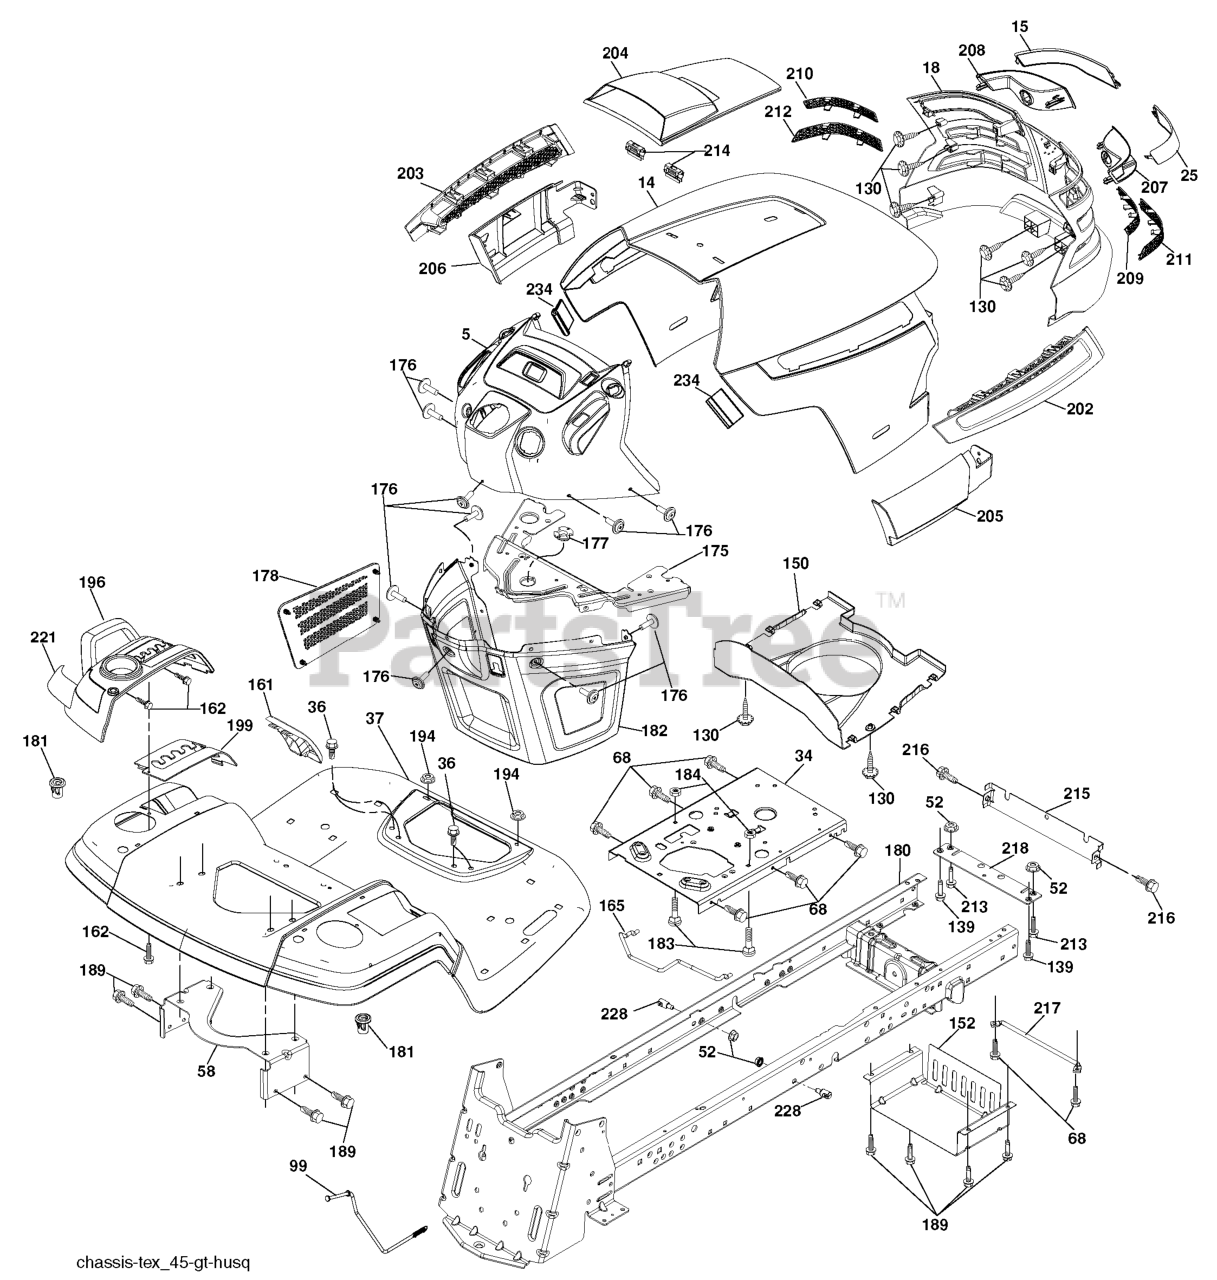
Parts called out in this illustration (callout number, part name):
5	DASH.HUSQ.UPR.ELE.SVMD
14	HOOD.PNT.HUSQVARNA.GT.
15	LENS.LH.TEX.GT.HUSQ.CL
18	GRILLE.ASM.TX.GT.HUSQ
25	LENS.RH.TEX.GT.HUSQ.CL
34	PLATE.ENGINE.WELDED.CHASSIS
36	SCREW 5/16"
37	FENDER.PNT.TX.GT.CH/FW.ORANGE
52	LOCKNUT
58	BRKT.SUPPORT.FNDR/TANK
68	Screw 5/16-18 x 1/2
99	ROD.ASM.BYPASS.0610.FE
130	SCREW
150	AIR.DUCT.TEXGT.HUSQ.SV
152	SHIELD.BROWNING.WTEXLT
161	CONSOLE.FUEL.WINDOW.HU
162	SCREW.HI-LO.CONSOLE
165	SUPPORT.TANK.REAR.W/TEX
175	PLATE.CROSSMEMBER.HUSQ
176	SCREW.#10-24X5/8.RN.QU
177	BUSHING, STEERING
178	CARGO.ASM.NET.TXGT.W/C
179	PLUG.N/CRUISE.COMMON.YT/GT.BLK
180	CHASSIS.WLDMT.TX.GT.05
181	BUSHING.MNT.FEND.CRGO.
182	DASH.LOWER.COMMON.12V.
183	BOLT.5/16-18X1-1/4 FULL.THREAD
184	SPACER.FENDER
189	SCREW
194	NUT LOCK HEX FLANGE 5/16-18
196	RP CONSOLE.ASM.DECKLFT.W/
199	PLATE.DECK.LIFT.HUSQVARNA.GT
202	VENT.SIDE.HOOD.HUSQ.RH.GREY
203	VENT.SIDE.HOOD.HUSQ.LH.GRAY
204	VENT.TOP.HOOD.HUSQVARN
205	SKIRT.HOOD.SIDE.HUSQ.RH.GREY
206	SKIRT.HOOD.SIDE.HUSQ.LH.GREY
207	BEZEL.RH.TEX.GT.HUSQ
208	BEZEL.LH.TEX.GT.HUSQ
209	INSERT.HEX.GRILL.HUSQ.GREY
210	INSERT.HEX.GRILL.HUSQ.
211	INSERT.HEX.GRILL.HUSQ.
212	INSERT.HEX.GRILL.HUSQ.
213	BOLT
214	CLIP.RETAINER.TINNER.
215	COVER.CHASSIS.FRONT.WE
216	SCREW, 5/16-18 X 1/2
217	ROD PIVOT CHASSIS/HOOD
218	X-PIECE.HOOD.STOP.NON/
221	REFLECTOR.LH.TEX GT HU
228	STUD.FASTNER.W/ANTI-ROTATE
234	BUMPER.HOOD.TEX.HUSQVARNA
